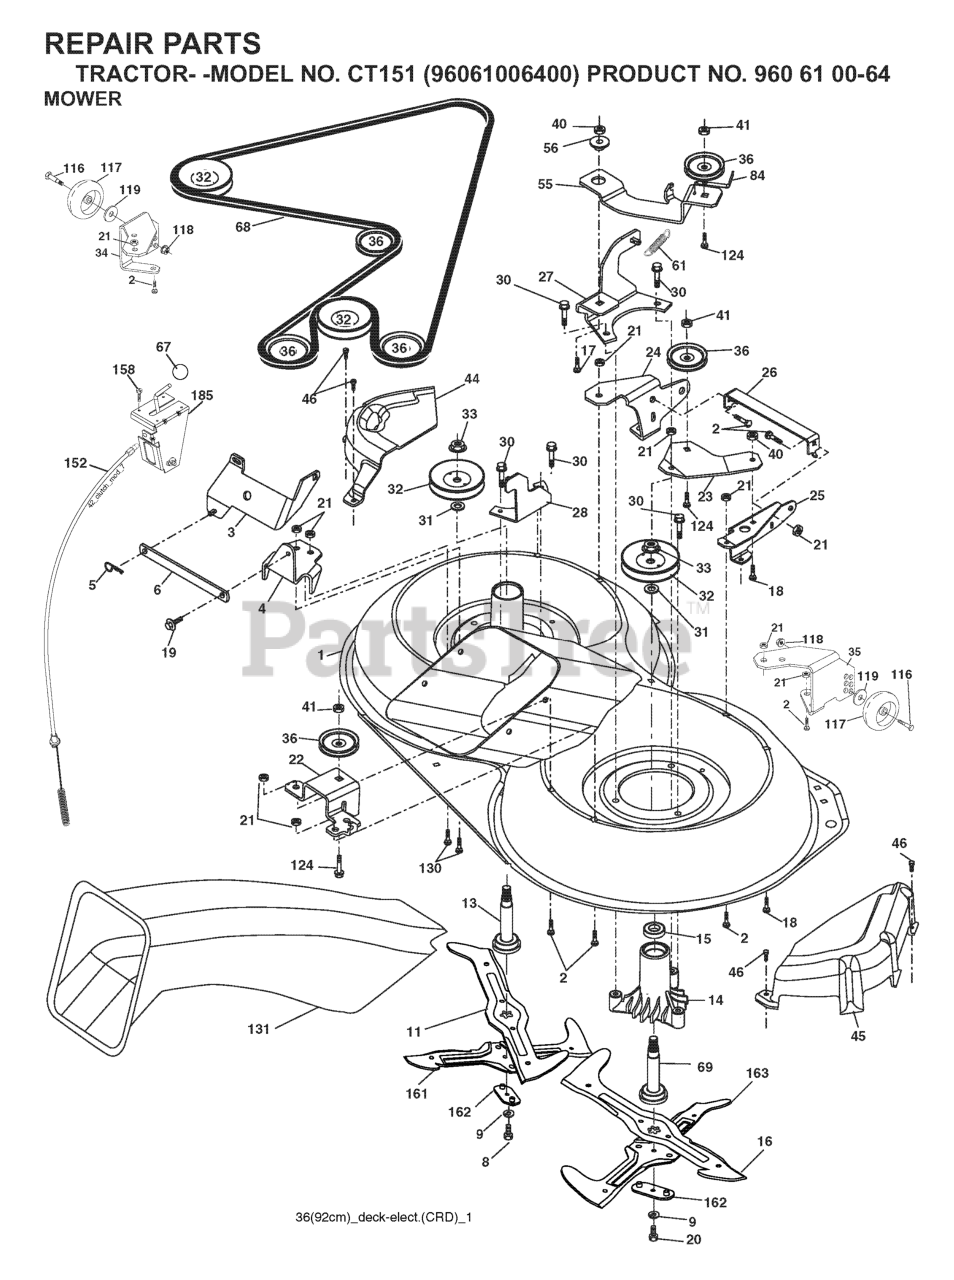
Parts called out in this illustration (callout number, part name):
2	RP BOLT 5/16-18 X3/4 ZN/YEL GR
5	RETAINER-SPRNG RB
6	BAR.SWAY.92.CRD
8	BOLT.3/8-24X1.25 GR8
9	LOCKWASHER
13	SHAFT ASM VENT
14	HOUSING.MANDREL.VENTED (MACHD)
17	BOLT.3/8-14X1.25
19	BOLT SHD 5/16-18
20	BOLT.3/8-24X1.25GR8. LHTHRD
21	LOCKNUT
26	SUPPORT
30	SCREW, WASHER HEAD
31	WASHER.SPACER.MANDREL
33	NUT.FLANGE.LOCK.TOP
36	PULLEY.IDLER.4.25
41	NUT LOCK FLG 3/8-16 UNC
45	COVER.MANDREL.RH.CRD
46	SCREW.1/4-20X5/8
55	ARM.IDLER.92 CRD.2006
56	SPACER.RETAINER.MOWER
61	SPRING
67	KNOB T (3/8 HOLE)
68	BELT.DRIVE.92CM.CRD.2006
69	SHAFT.ASM.W/LWR.BRG.RH.THREAD
84	KEEPER, BELT IDLER
116	SHOULDER BOLT
117	RP WHEEL. GUAGE RALLY
118	LOCKNUT
119	WASHER.5/16.FLAT.STE.STD.
124	BOLT.3/8-16X1.50
130	BOLT.CARR.SQNK.5/16-18UNC.X3/4
131	CHUTE BAGGER
158	SCREW
185	HEAD ASM. CABLE CLUTCH
